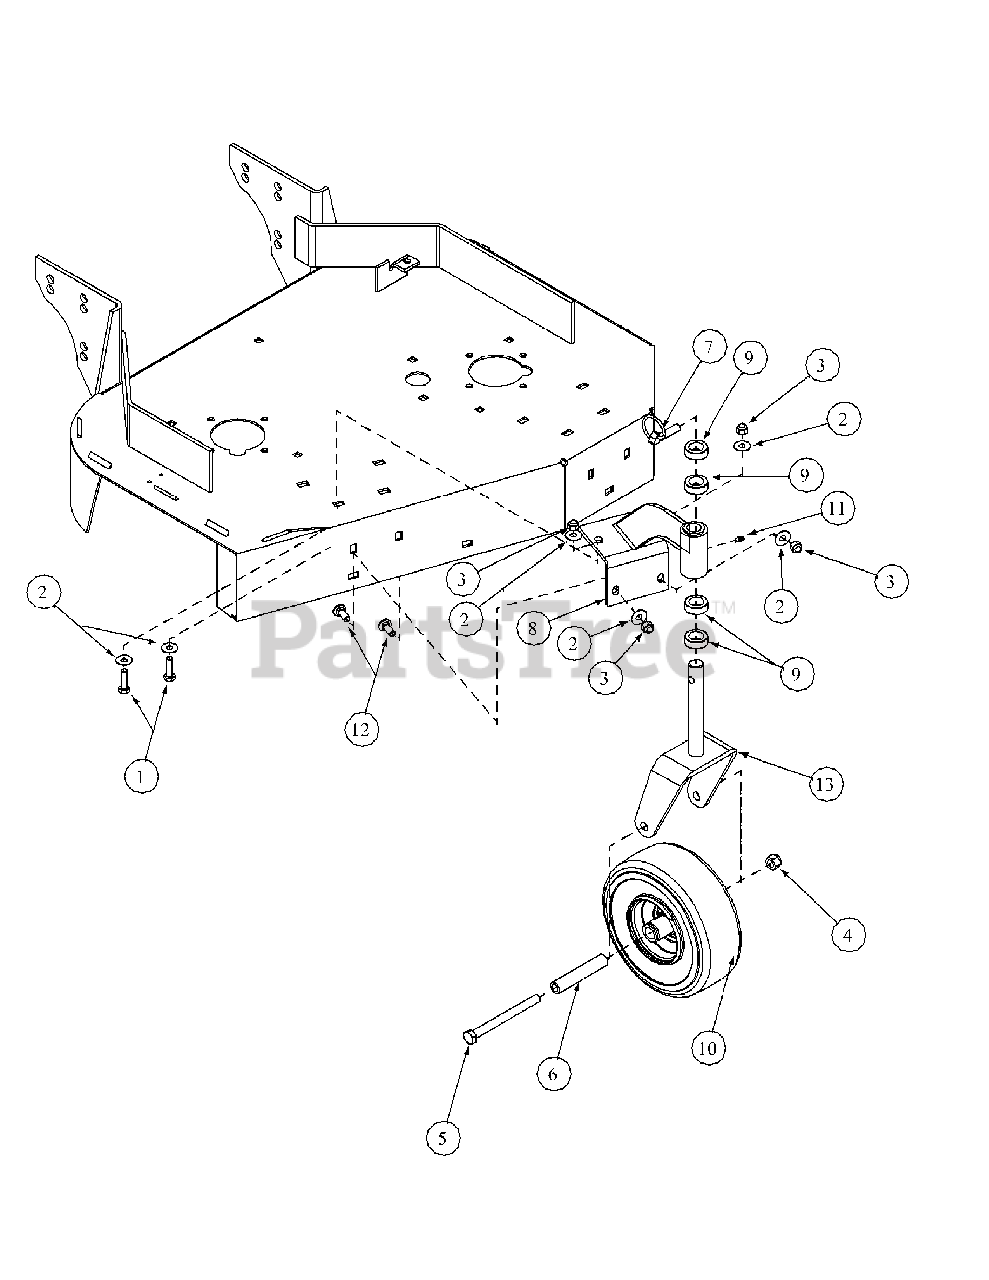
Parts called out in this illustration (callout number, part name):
1	Hex Cap Screw, 3/8-16 x 1-1/4
2	Flat Washer, 3/8 Zinc
3	Lock Nut, Nylon Insert, 3/8-16
4	Lock Nut, Nylon Insert, 1/2-13
5	Hex Cap Screw, 1/2-20, 5.50
6	Spacer Wheel
7	Klik Pin, 1.75
8	Caster Bracket Weldment
9	Spacer, Caster
10	Wheel Assembly, 9.0 x 3.50-4
11	Grease Fitting, 1/4-28 x 3/16
12	Carriage Bolt, 3/8-16 x 2
13	Caster Yoke Assembly, Weldment
